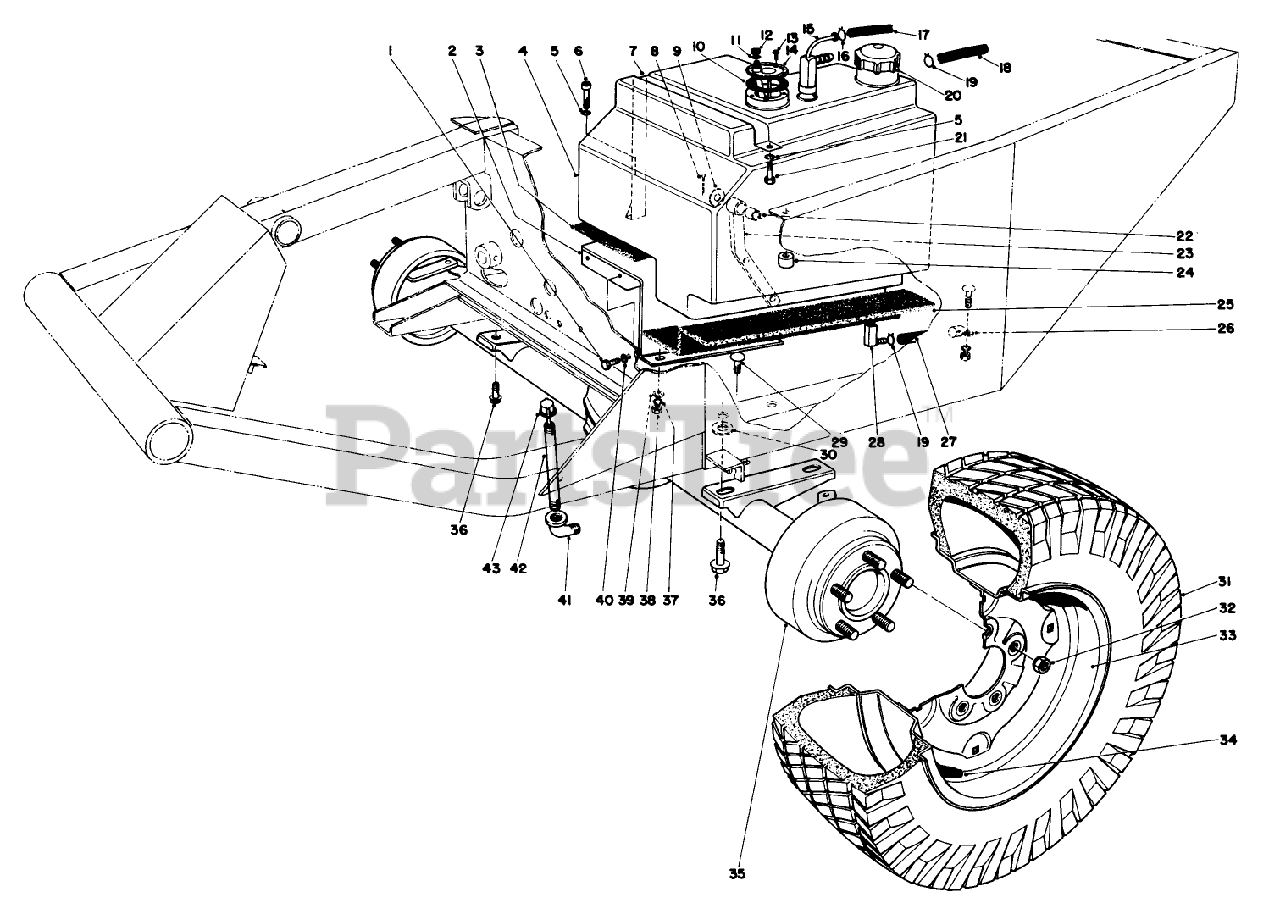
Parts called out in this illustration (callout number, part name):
1	Capscrew
2	GAS TANK BASE WA
3	FOAM-SUPPORT, TANK
4	Fuel Tank (Incl. Ref. #15 & 28)
5	WASHER-LOCK
6	SCREW-HSH
7	STRAP-TANK, FUEL
8	PIN-COTTER
9	WASHER-THRUST
10	Gasket
11	WASHER-LOCK
12	NUT-HEX
13	SCREW-SHWH, THREAD FORMING
14	FUEL LEVEL SENDER
15	FITTING-RETURN AND VENT
16	CLAMP-HOSE
17	HOSE-RETURN
18	HOSE-VENT, GAS TANK
19	CLAMP-HOSE
20	Gas Cap
21	SCREW-HH
22	BUSHING
23	Steering Link (Incl. Ref. #22)
24	SPACER
25	FOAM-SUPPORT, TANK
26	CLAMP-R
27	Hose Fuel
28	FITTING ASM
29	BOLT-CARR
30	SPECIAL WASHER
32	NUT-LUG
34	STEM-VALVE
35	AXLE WA RO
36	SCREW-HHF
37	WASHER-LOCK
38	NUT-HEX
39	WASHER-PLAIN
40	WASHER-LOCK
41	FITTING-ELBOW-90
42	NIPPLE-PIPE
43	DIPSTICK ASM
